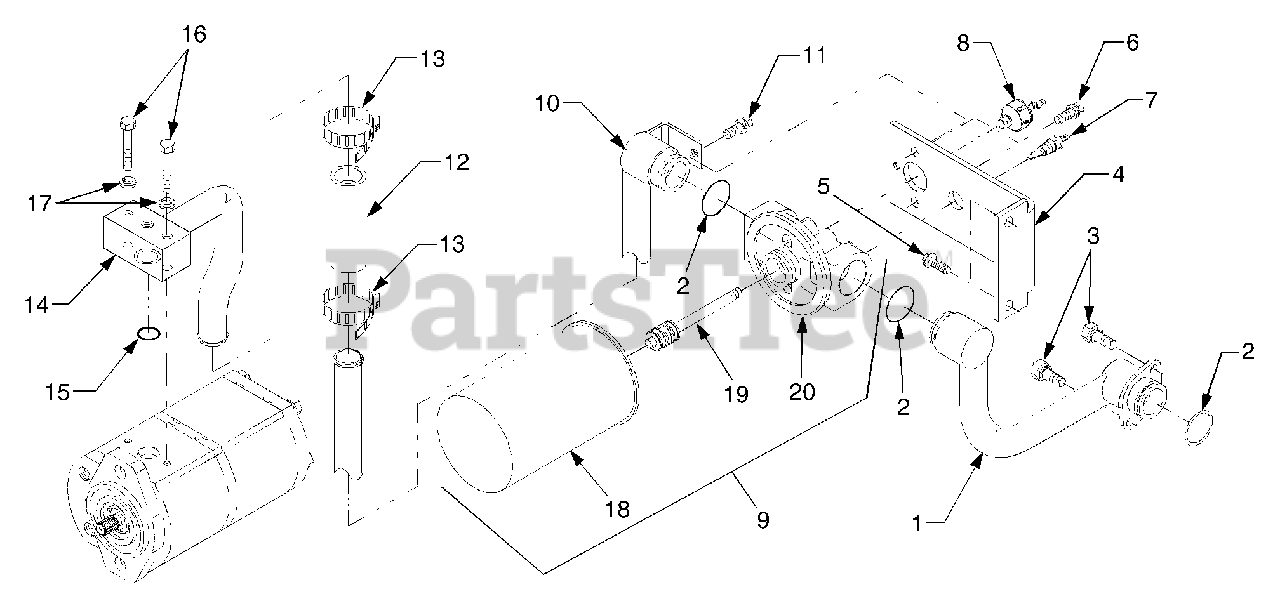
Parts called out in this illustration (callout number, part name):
1	Pipe 1, Suction
4	Support, Filter
7	Sensor, Thermostat
8	Sensor, Vacuum
9	Hydraulic Filter Ass'y
10	Pipe 2, Suction
14	Pipe 3, Suction
17	Washer, Spring
18	Filter, Hydraulic
19	Magnetic Ass'y
20	Bracket, Filter
